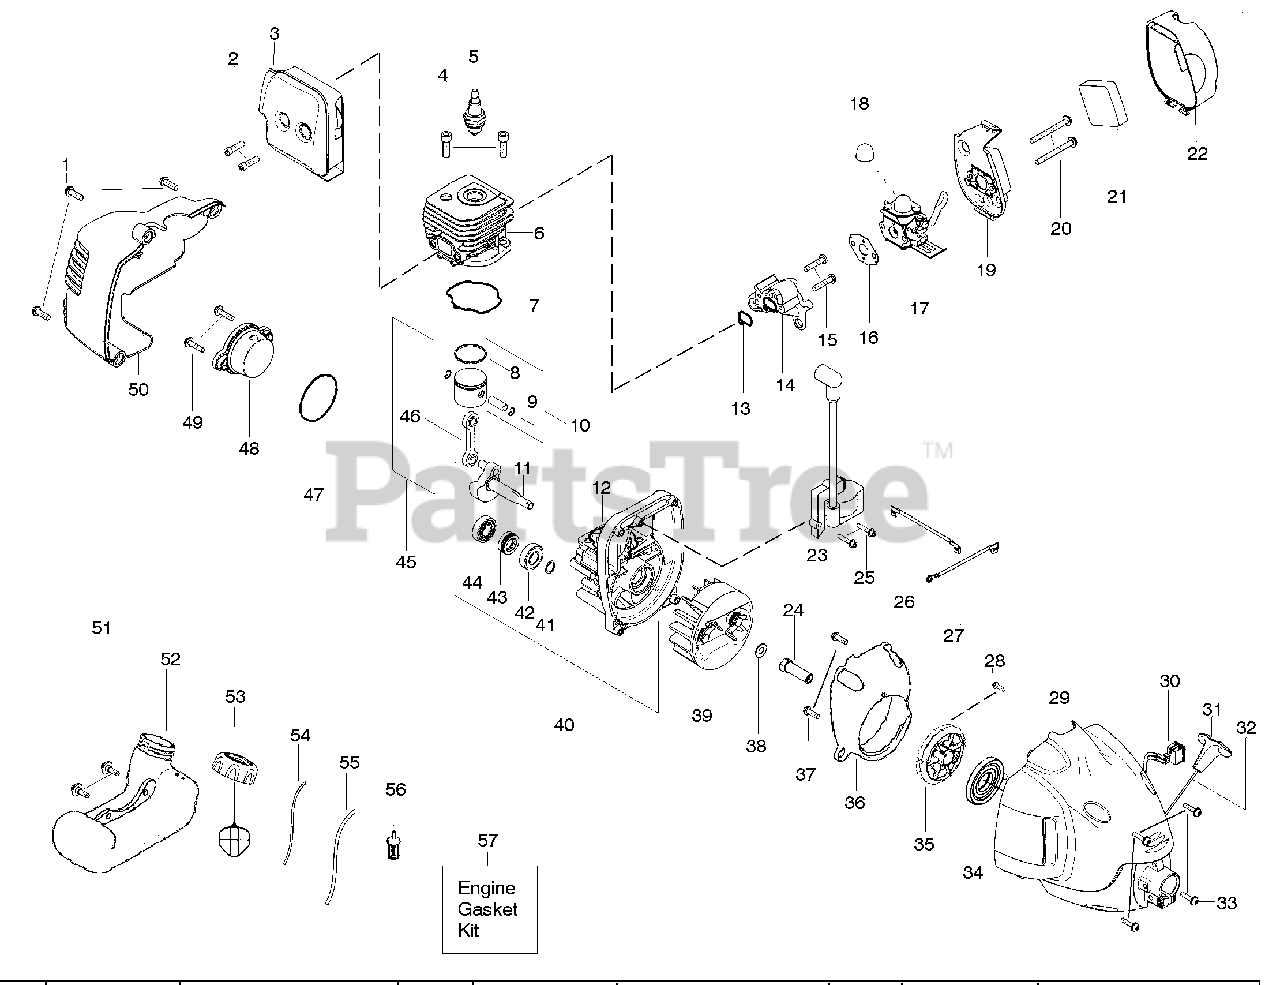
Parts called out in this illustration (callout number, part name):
3	Assy-Muffler/Shield
4	Screw-Cylinder
5	Spark Plug (RCJ 6Y)
7	Seal-Cylinder (kit)
8	Piston Ring
9	Retainer-Piston Pin
10	Kit - Piston
11	Assy-Crankshaft
12	Assy-Crankcase
13	Seal-Cyl/Carb.(kit)
14	Adapter-Carb.
16	Gasket-Carb. (kit)
17	Kit-Carb Zama (C1U-W24)
17	Kit-Carb Walbro ( WT-670)
18	Purge Bulb Zama
18	Purge Bulb Walbro
19	Air Box
21	Foam-Air Filter
22	Cover-Air Box
23	Ignition Module
24	Coupling-Drive
26	Assy-Leadwire
27	Assy-Ground Wire
29	Assy.-Fan Hsg
31	Handle-Starter
34	Spring-Starter
35	Kit-Starter Pulley
39	Assy-Flywheel
40	Assy-C'case & C'shaft
41	Retain. Ring-C'shaft
42	Outer Bearing
44	Inner Bearing
45	Kit-Piston/Rod
46	Assy-Connecting Rod
47	O-Ring-C'case (kit)
48	Assy-Plug
51	Retainer-Tank
52	Assy-Fuel Tank
53	Assy-Fuel Cap
54	Kit-Fuel Line (Small)
55	Kit-Fuel Line (Large)
56	Assy-Fuel Pickup
57	Kit-Engine Gasket
